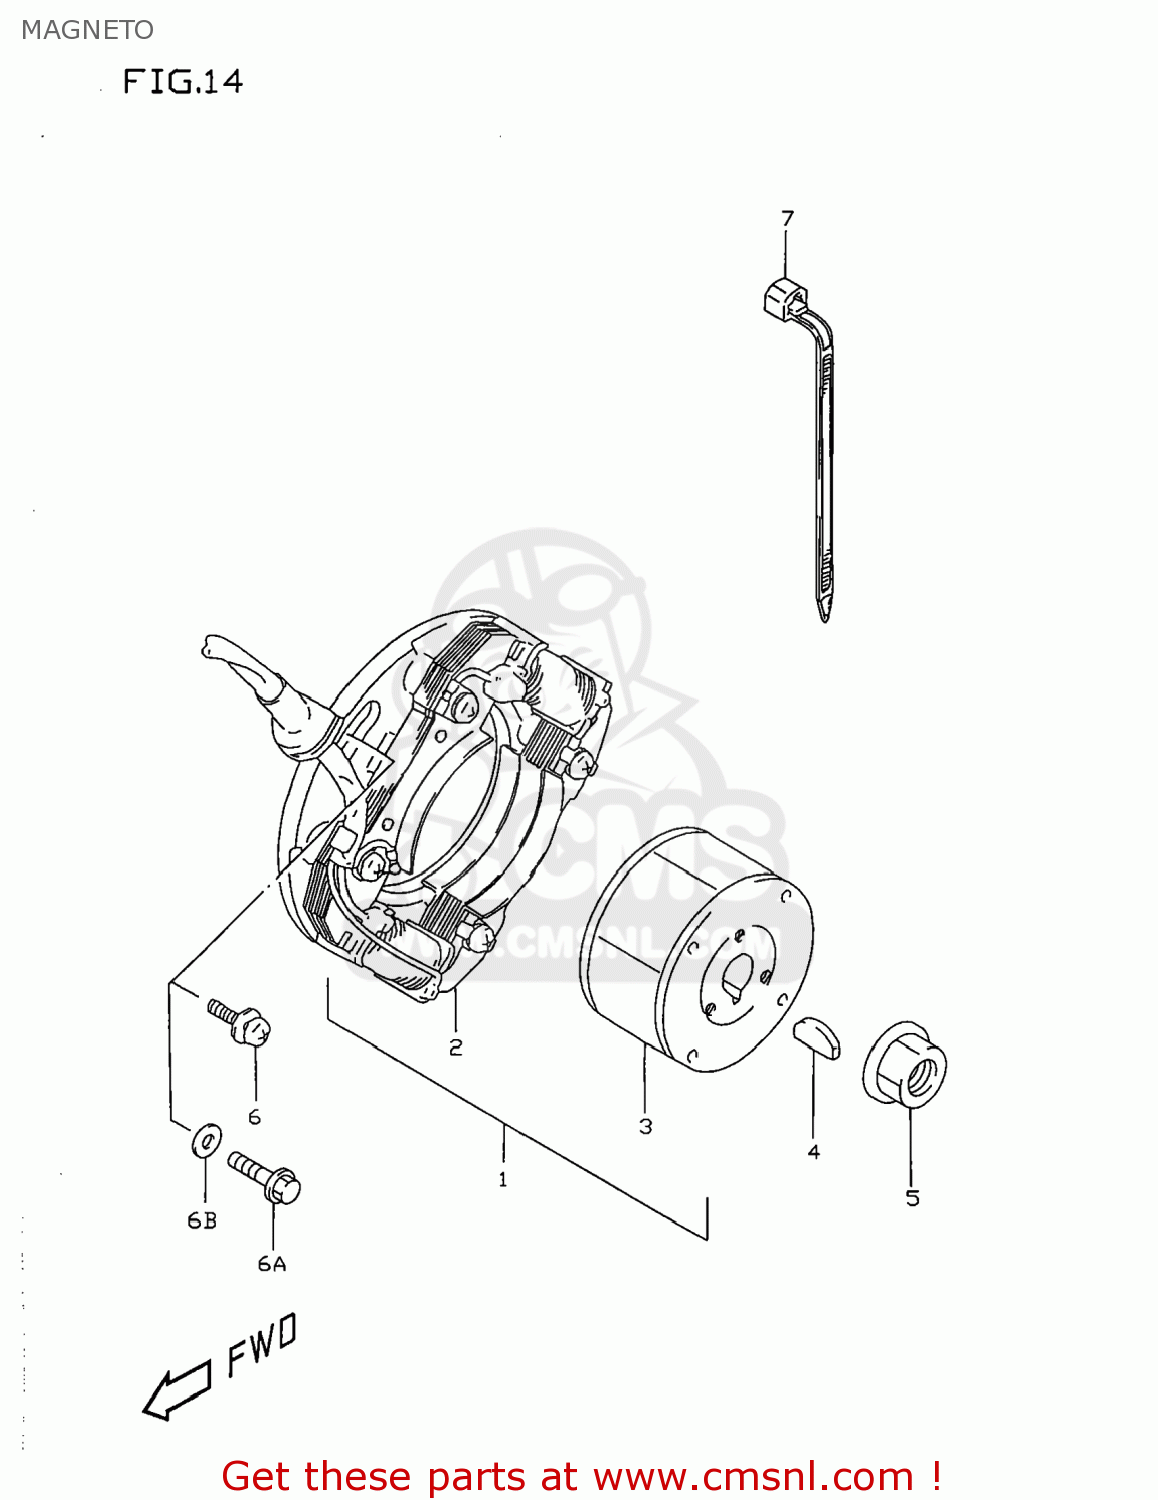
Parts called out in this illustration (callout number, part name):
1	MAGNETO ASSEMBLY
2	STATOR
3	ROTOR
4	KEY
5	NUT
6	SCREW
6A	SCREW
6B	WASHER
7	CLAMP L:165
